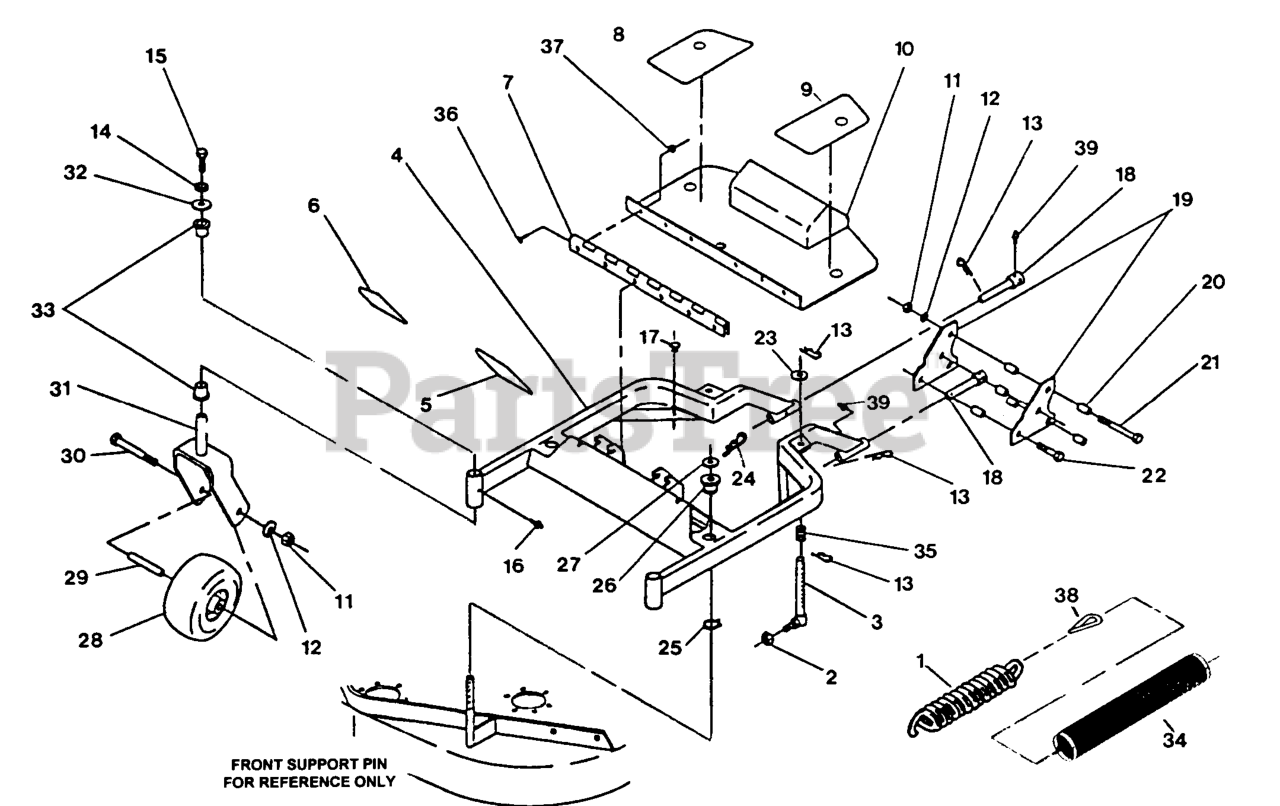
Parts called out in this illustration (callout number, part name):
5	PAD,ANTI SKID UPPER LH
6	PAD,ANTI SKID UPPER RH
7	HINGE,FLOORPAN
8	PAD,ANTI SKID LOWER RH
13	PIN,HAIR COTTER
18	PIVOT MOUNT W/ZERK PLTD
26	BUSHING-DECK
27	WASHER-FLAT
33	BEARING-FLANGED
35	SPRING,HITCH RELEASE
